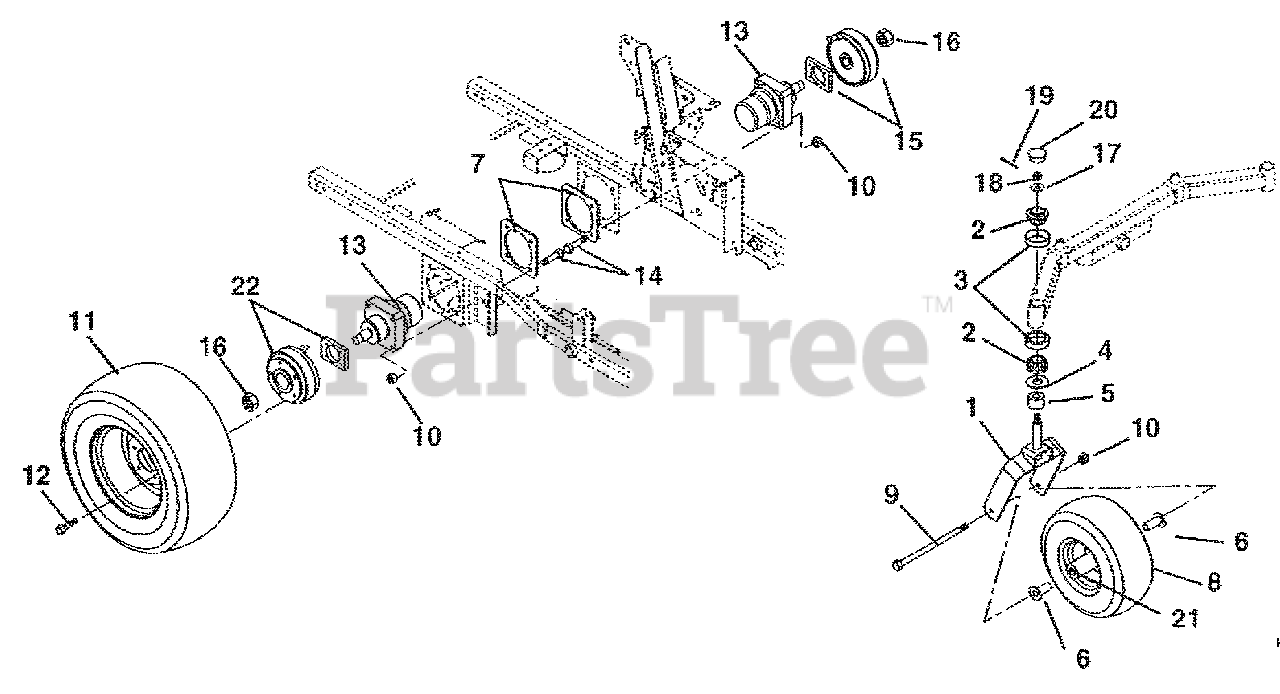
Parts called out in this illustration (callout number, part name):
1	Fork, Front
2	Bearing, Cone w/ Grease
3	Bearing, Cup 1.980 x .420
4	Bearing Seal 1.5 x 2 x .18
5	Spacer, PM, 1.03 I.D. x 1.5 O.D. x .375
6	Spacer, Wheel
7	Plate, Motor Support
8	Wheel/Tires Assembly
9	Bolt, Hex .50-13 x 9.00 Grade 5
10	Nut-Locking-Top-Flange .50-13
11	Tire/Wheel Assembly 24 x 12-12
12	Bolt, Lug .50-20 x 1.38 Grade 8, 60 Degrees
13	Hydraulic Wheel Motor (includes 16)
14	Bolt, Wheel Motor .50-13 x 2.75
15	Brake, Right Hand Park
16	Nut, Lock Jam Patch (Included with 13)
17	Washer, Flat Steel .755 x 1.375 x .062
18	Nut, Slotted .75-16
19	Pin, Cotter .16 x 1.00
20	Cap, Dust
21	Bearing, 25mm I.D. x 52mm O.D. x 15mm
22	Brake, Left Hand Park
